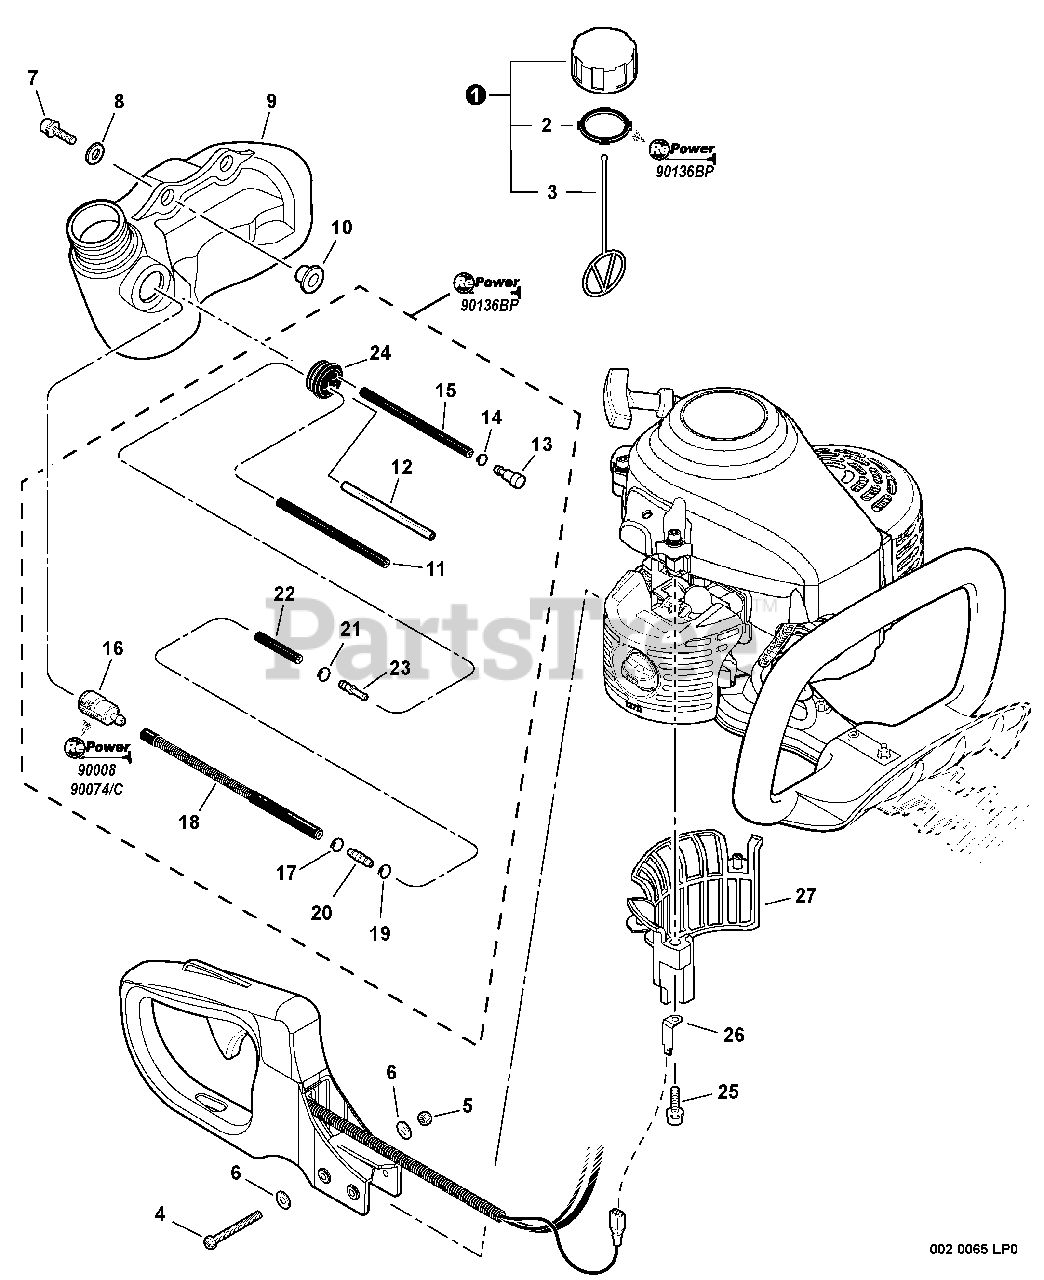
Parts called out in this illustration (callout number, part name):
1	CAP ASSY - ORANGE
2	GASKET, CAP
3	CONNECTOR, CAP
4	SCREW - 5X45
5	LOCKNUT - 5
6	WASHER - 5
7	SCREW - 5X20
8	WASHER - 5
9	TANK, FUEL
10	COLLAR - 5
11	PIPE - 3X5X61 -- BLACK
12	PIPE - 3X6X75 -- CLEAR
13	VENT, FUEL TANK
14	CLIP - 6
15	PIPE - 3X6X50 -- BLACK
16	FILTER, FUEL
17	CLIP - 6.6
18	PIPE, FUEL - CORRUGATED
19	CLIP - 6.5
20	CONNECTOR, PIPE
21	CLIP - 6.5
22	PIPE - 3X6X35 -- BLACK
23	CONNECTOR, PIPE
24	GROMMET
25	SCREW - 5X16
26	TERMINAL - GROUND
27	GUARD, DEBRIS
28	RePower FILTER KIT
29	RePower TUNE-UP KIT
30	RePower FUEL SYSTEM KIT
